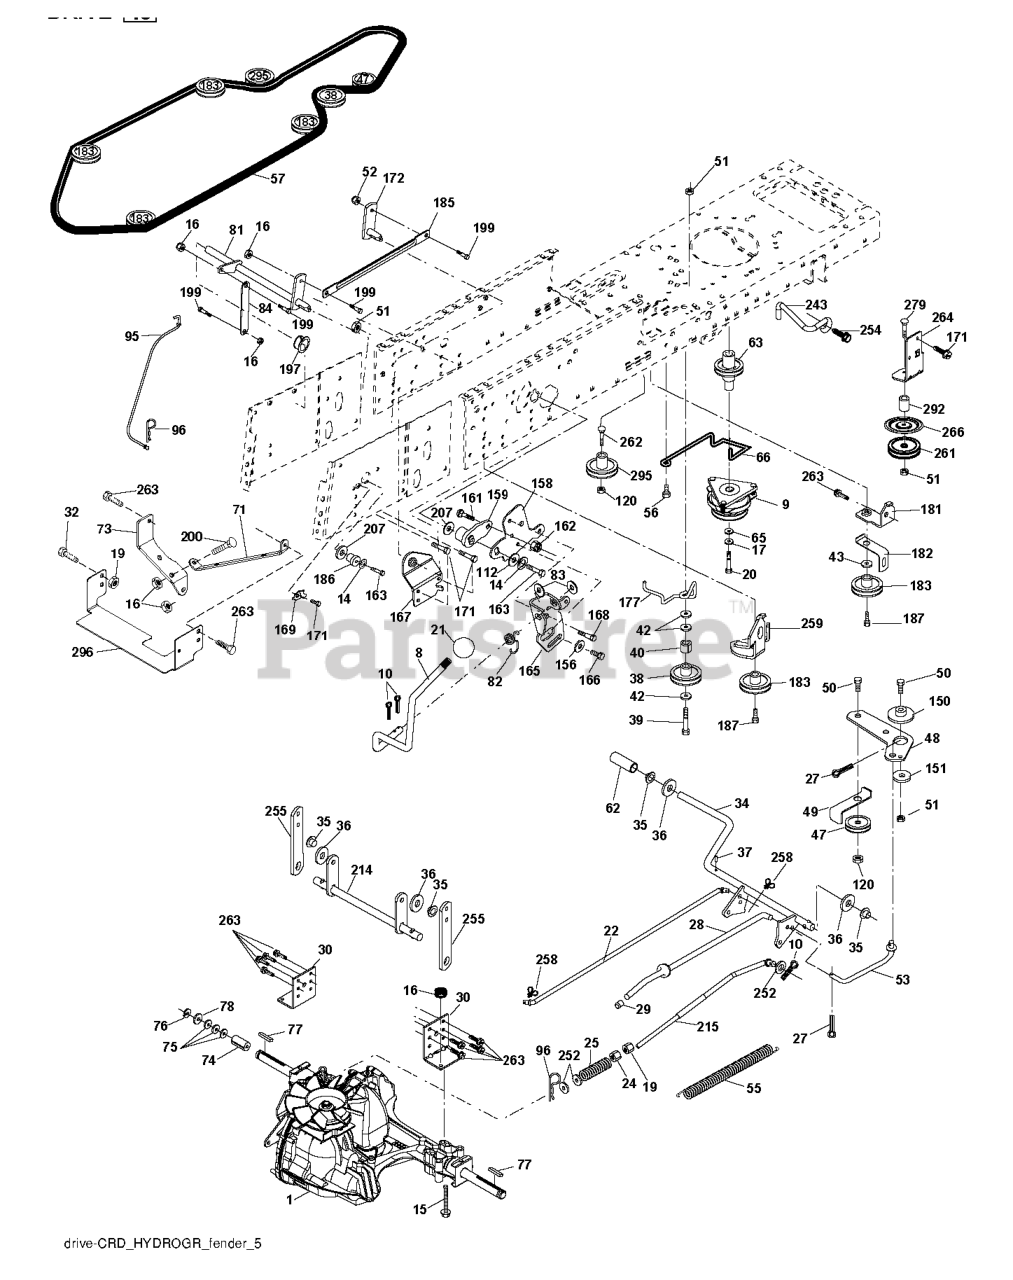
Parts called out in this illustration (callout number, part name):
8	ROD SHIFT FENDER ADJUST LT
9	CLUTCH.ELECTRIC.OGURA.EURO.
10	PIN COTTER
14	LOCKWASHER
15	BOLT HEX 5/16-18 GR 5
16	NUT.71038.31-18.HEX.NYLOCK
19	NUT
20	BOLT HEX 7/16-20X4-1/4"
21	KNOB.DUCKHEAD.1/2
22	ROD
24	NUT
25	SPRING BRAKE ROD
27	COTTER PIN
28	ROD, PARKING BRAKE
29	PLUNGER CAP
30	BRKT, TRNSXLE MNT 20"
34	SHAFT, FOOT PEDAL
35	BEARING.NYLON
37	DRIVE PIN
38	PULLEY.FLAT
42	WASHER
47	IDLER PULLEY
48	BELLCRANK, CLUTCH
49	RETAIN BELT
50	BOLT.3/8-16X1.50
52	LOCKNUT
53	LINK.CLUTCH.7.66.2005
55	SPRING, RETURN LT
56	SCREW.3/8-16
57	V-BELT 113"
62	PEDAL COVER T
63	PULLEY.ENGINE.CVX.LT
65	LOCKWASHER
66	KEEPER BELT ENGINE
71	STRAP TORQUE LH HYDRO
73	STRAP TORQUE RH HYDRO
74	SPACER AXLE
77	SQUARE KEY
81	ASM.CROSS.SHAFT.REAR.CRD.0510
82	SHIFT SPRING
83	WASHER
84	LINK.PNT.TRANSAXLE.0510.CRD
95	LINK
96	RETAINER M
120	NUT LOCK FLG 3/8-16 UNC
150	BUSHING.BELLCRANK.GRD.DR
151	WASHER 12/32X2X10GA
156	WASHER.SRRTD.5/16
158	BRACKET
159	RB HUB.SHIFT
161	BOLT
162	NUT.CROWNLOCK.1/4
165	RP BRACKET
166	CAPSCREW.HXHD.FLG.5/16-18X.625
167	BRACKET.SUPT.SHIFT.CRD
168	BOLT.SHOULDER.5/16-18X
169	PLATE.FASTENING.CROSS.SHAFT
172	LINK
181	BRACKET
182	BELT GUIDE
183	PULLEY.V-IDLER.GRND.DR
185	LINK
186	HUB.TAPERED.ROUND.CRD
187	BOLT.5/16-18X1.25
197	NYLINER SNAP 5/8" ID
199	BOLT SHOULDER 5/16-18 UNC
207	WASHER NYL
214	LEVER
215	ROD
243	BRACKET, ANTI-ROTATION
252	WASHER
254	SCREW 3/8-16X1
255	SHAFT
258	CLIP RETAINER
259	BRACKET
261	FLAT IDLER PULLEY
263	SCREW, 3/8-16X3/4
266	PROTECTOR
292	SPACER
295	PULLEY IDLER COMPOSITE
